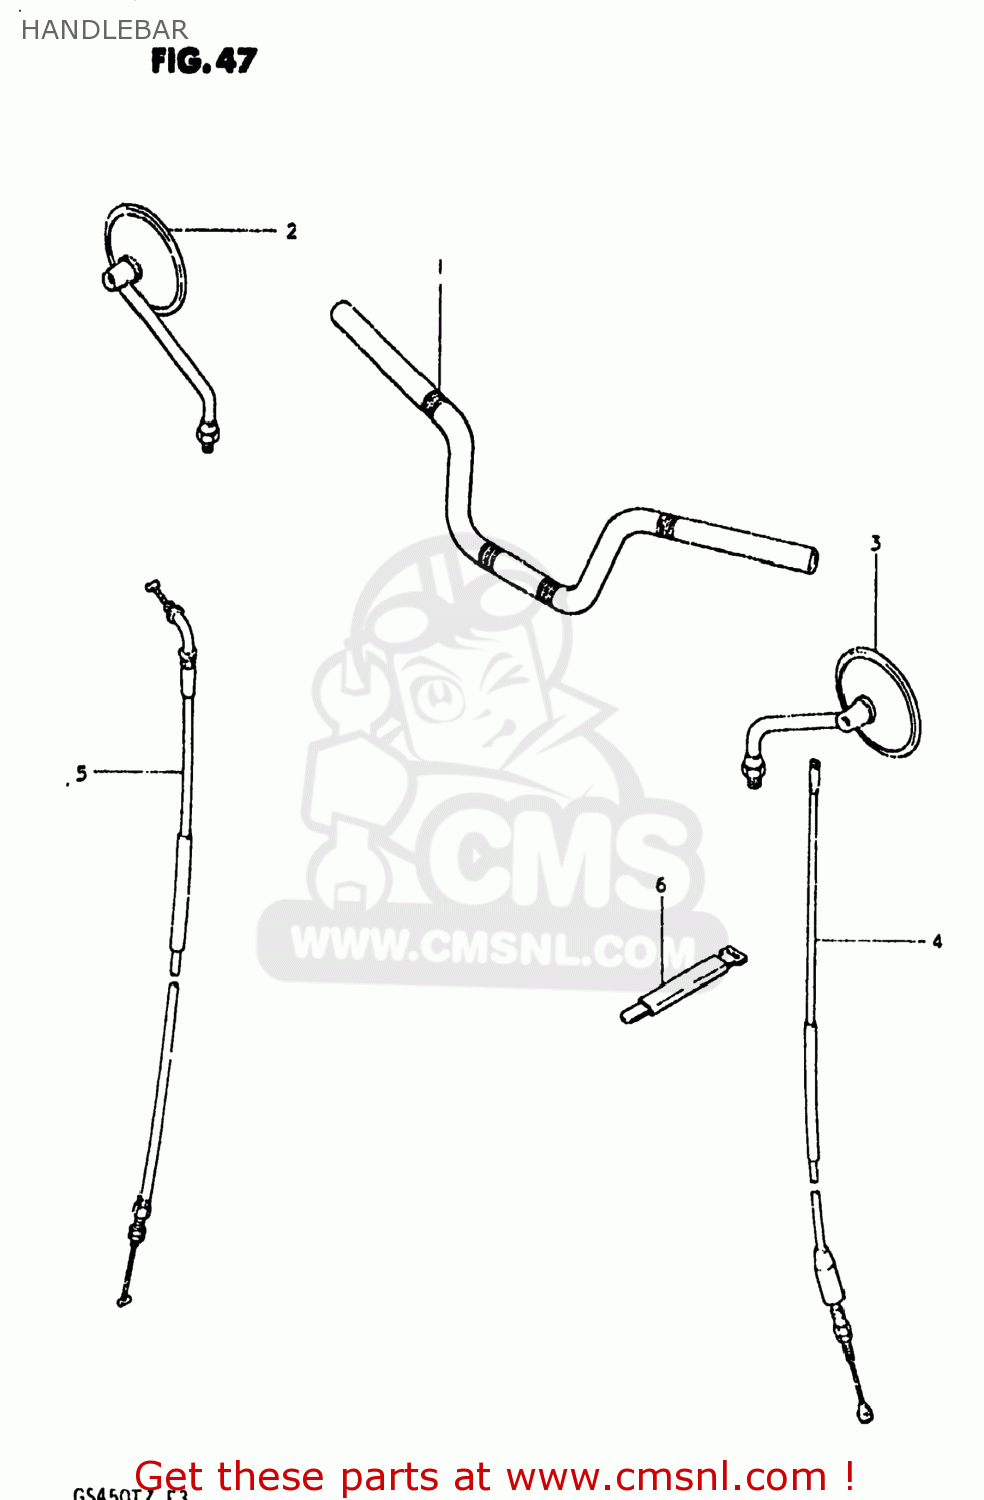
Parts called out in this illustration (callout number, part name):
1	HANDLEBAR
2	MIRROR ASSEMBLY,RIGHT
3	MIRROR ASSEMBLY,LEFT
4	CABLE ASSEMBLY,CLUTCH
5	CABLE ASSEMBLY,THROTTLE
6	CLAMP
